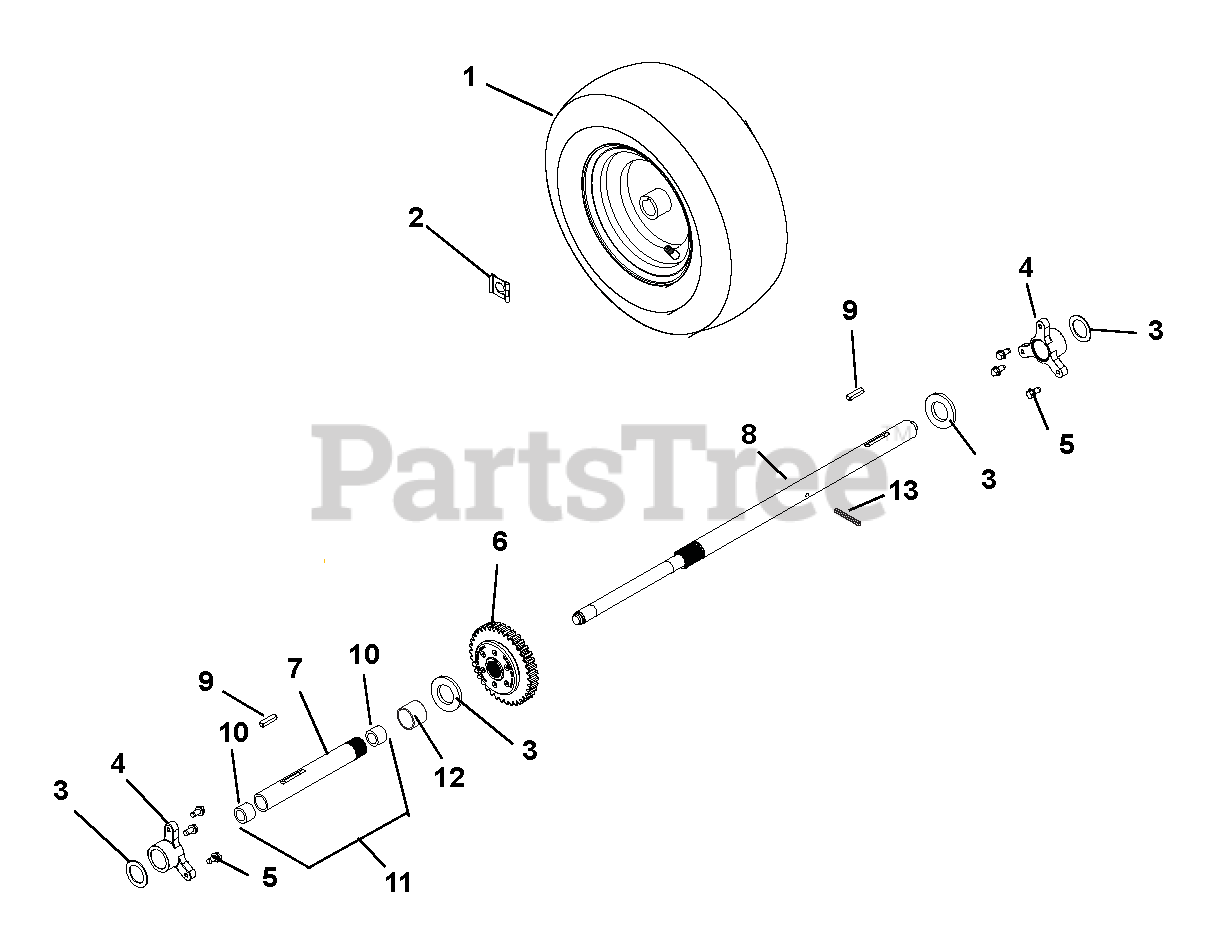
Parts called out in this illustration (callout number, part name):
1	TIRE/WHEEL,RH 15X5.00-6 REMOTE
1	TIRE/WHEEL,LH 15X5.00-6 REMOTE
1	TIRE, 15X5.00-6 K478
1	TUBE 15 X 5.00-6
2	CLIP, SNAP .625 DIA
3	WSHR-FL-STL 1.010X1.505X.062YZ
4	BUSHING, AXLE
5	SCR-TAP .25-20X.50 HWH TR YWZ
6	DIFFERENTIAL, AUTOMATIC
7	AXLE, SHORT - DIFFERENTIAL
8	AXLE, LONG - DIFFERENTIAL
9	KEY-RECT .25X.188X1.00
10	BSHG-SLV .706X.764X.75 BRZ
11	AXLE, DIFFERENTIAL W/BUSHINGS
12	BSHG-SLV, 1.012X1.125X1.00
13	PIN-ROLL .188X1.25
